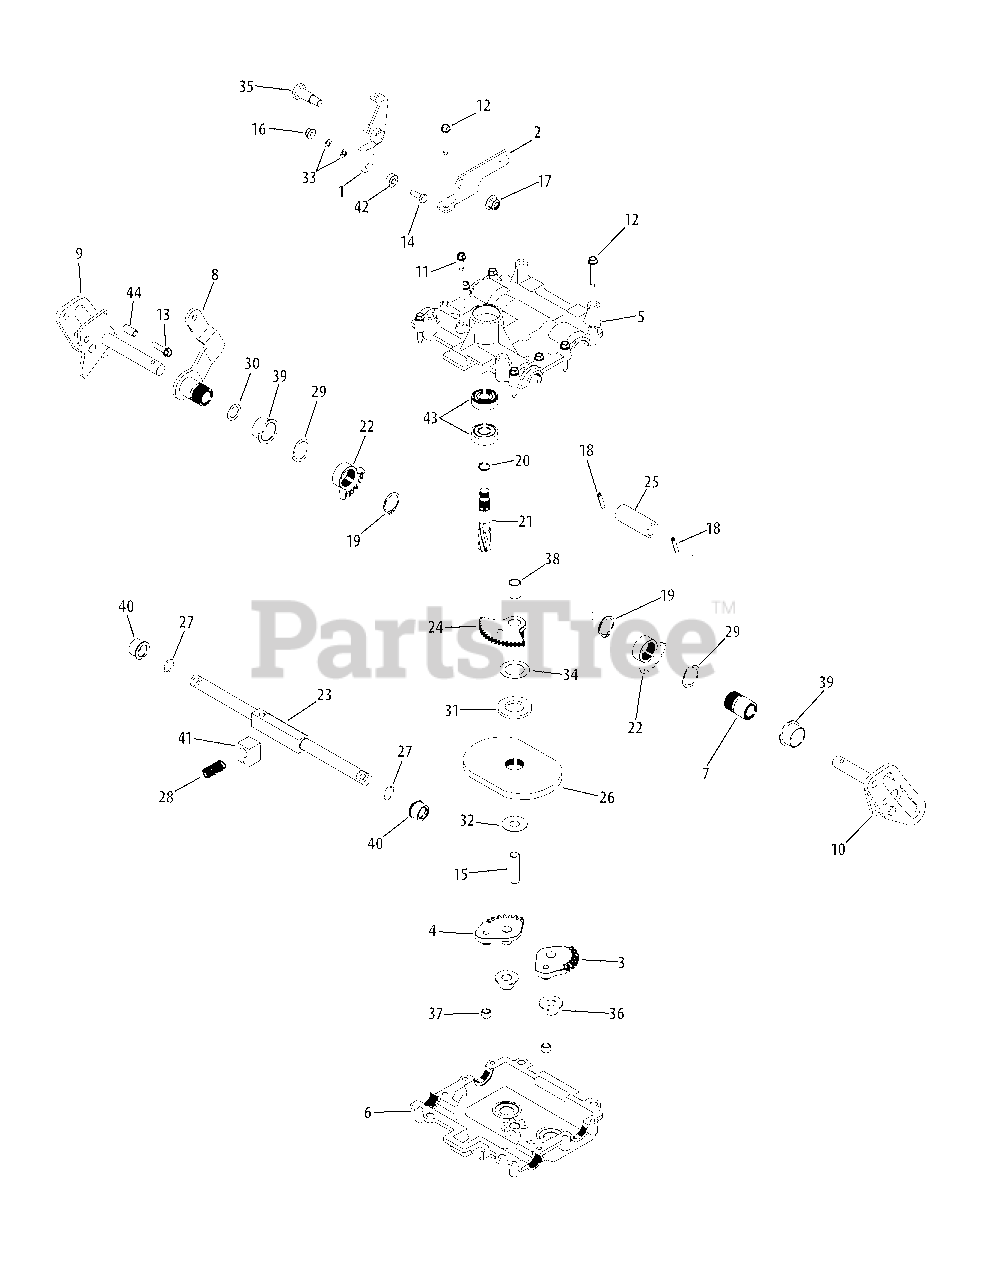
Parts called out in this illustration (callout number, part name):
1	Cam Plate Assembly
2	Neutral Bracket
3	LH Steering Gear Assembly
4	RH Steering Gear Assembly
5	Upper Steering Housing
6	Lower Steering Housing
7	Vertical Hydro LH Arm Assembly
8	Vertical Hydro RH Arm Assembly
9	RH Cam Assembly
10	LH Cam Assembly
11	Hex Washer Screw, 1/4-20 x 0.750
12	Hex Washer Screw, 1/4-20 x 1.500
13	Hex Washer Screw. 1/4-20 x 1.000
14	Hex Screw, 1/4-20 x .75
15	Steering Shaft
16	Hex Lock Nut, 1/4-20
17	Flange Lock Nut, 3/8-16
18	Spirol Pin, 3/16 x 1.00
19	Snap Ring, 1.0
20	Retaining Ring, .56
21	Pinion Gear, 7-Tooth
22	Steering Gear, 26-Tooth
23	Synchro Rack Gear
24	Steering Gear, 53-Tooth
25	Speed Cam Tube
26	Hydro Steering Cam
27	O-Ring, .625 x .07
28	Compression Spring, .531 x 1.25
29	Wave Spring, 24.22 x 32 x 1.98
30	Flat Washer, .635 x .930 x .033
31	Flat Washer, 1.01 x 1.75 x .172
32	Flat Washer, .508 x 1.325 x .040
33	Flat Washer, .260 x .455 x .048
34	Thrust Washer, 1.007 x 1.542 x .03
35	Shoulder Screw, 3/8-16 x .500 x .835
36	Flange Bearing, .5 x .700
37	Sleeve Bearing, .437 x .3425
38	Sleeve Bearing, .623 x .5025 x .800
39	Sleeve Bearing, 1.2 x 1.00
40	Flange Bearing, .625 x .875
41	Rack Caster Bearing
42	Ball Bearing, .25 x .6875 x .25
43	Ball Bearing, .5625 x 1.375 x .4375
44	Spacer, .260 x .375 x .75
